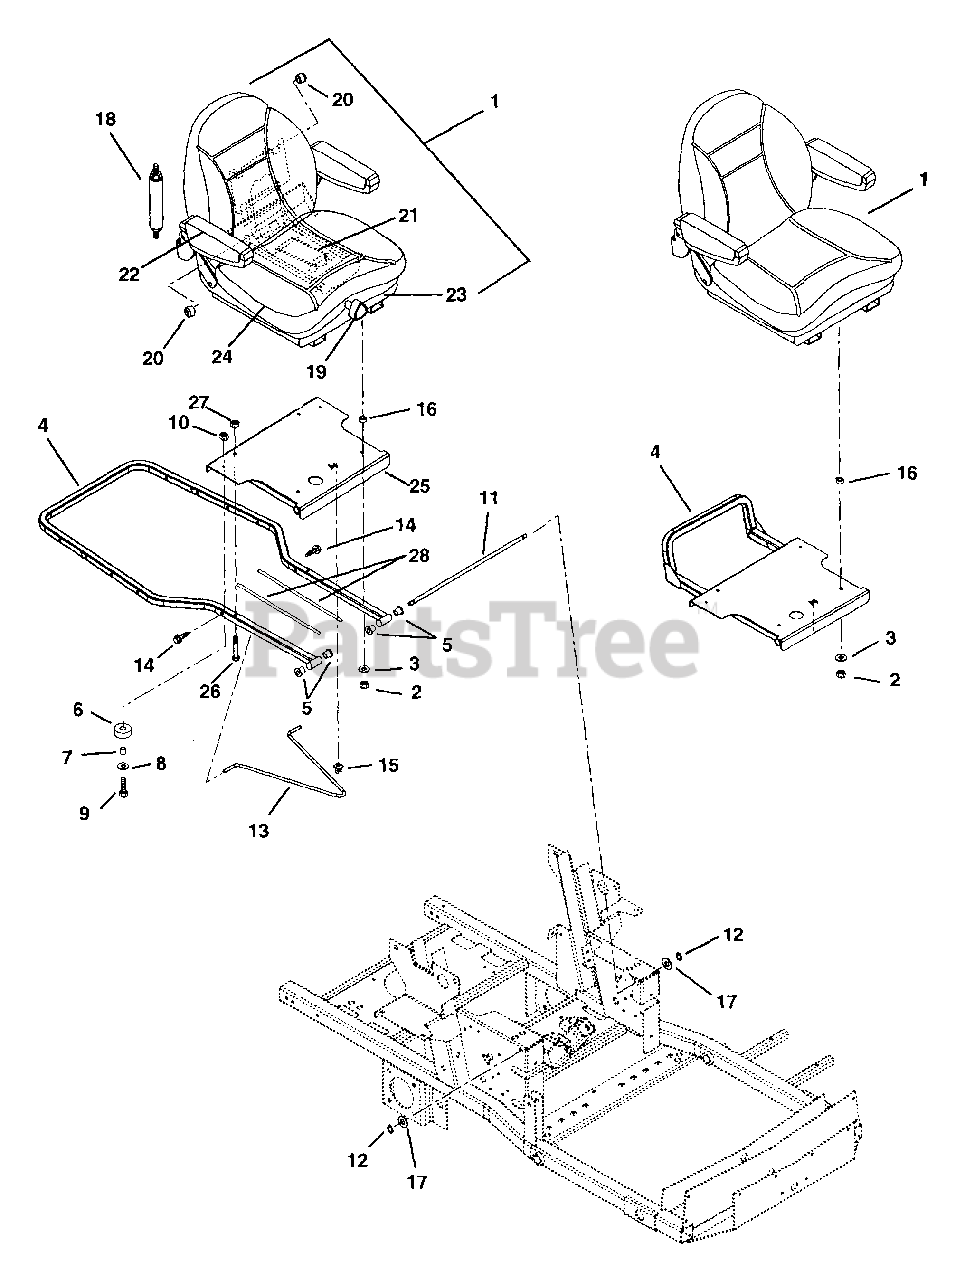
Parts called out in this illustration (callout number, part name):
1	Seat-Suspension
2	Nut-Locking-Center M8-1.25
3	Washer-Flat-Steel .38 x .875 x .083
4	Weldment- Hood Frame
4	Weldment - Seat Frame
5	Bushing-Flange .515 x .750 x .745 x 1.00
6	Bumper-Seat
7	Bushing-Sleeve .265 x .375 x .250
8	Washer-Flat-Steel .312 x .734 x .065
9	Bolt-Hex .25-20 x .75 Grade 5
10	Nut-Locking-Center .25-20
11	Rod-Seat Frame Pivot
12	Ring-Retaining-External .500 x .050
13	Rod-Prop
14	Screw-Tapping .25-20 x .50 Hex Washer Head
15	Clip
16	Bushing-Sleeve .377 x .624 x .235
17	Washer-Flat-Steel .531 x 1.06 x .095
18	Kit-Damper w/Hardware
19	Kit-Knob
20	Kit-Roller
21	Kit-Spring Cable
22	Kit-Arm Pad
23	Kit-Adjuster
24	Kit-Cushion
25	Weldment-Seat Pivot Plate
26	Bolt-Rib Neck .38-16 x 1.50
27	Nut-Locking-Top-Flange .38-16
28	Tape-VHB 4941F
